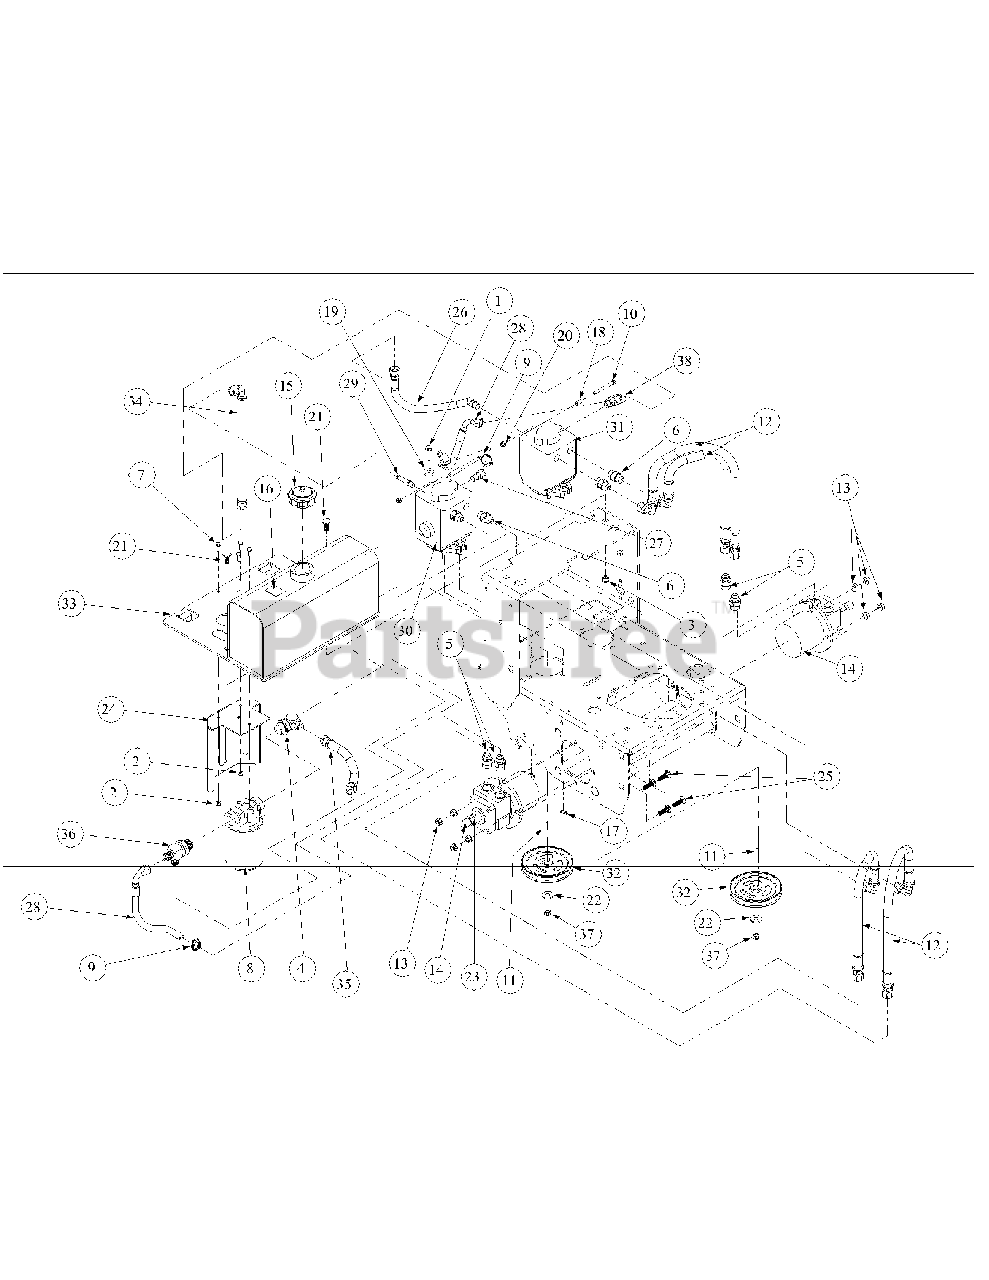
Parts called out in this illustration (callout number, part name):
1	Cap Screw, Standard, 3/8-16 x 1-1/4
2	Lock Nut Nylon Insert, 1/4-20
3	Lock Nut, 3/8-16
4	Elbow 90° 1/2 x 3/4
5	Fitting, Aeroquip
6	Fitting, Aeroquip
7	Cap Screw, 1/4-20 x 3/4
8	Filter Head 3/4
9	Worm Gear Clamp, 5/16-7/8
10	Cap Screw, Socket Head, 1/4-20 x 1-1/2 Zinc
11	Key, 3/16" x 7/8"
12	Reverse Pressure Hydraulic Hose Assembly
13	Flange Lock Hex Nut, 3/8-16
14	Hydraulic Motor, Wheel
15	Cap, Hydraulic Oil Tank
16	Oil Label, 20W-50
17	Lock Nut, 3/8-16
18	Spacer, Pump Release
19	Washer, Idler
20	Hex Lock Nut, 1/4-20
21	Carriage Bolt, 3/8-16 x 1.0
22	Bell Washer, .396 x 1.140 x .095
23	Woodruff Key, 3/16 x 3/4
24	Filter Guard Weldment
25	Carriage Bolt, 3/8-16 x 1.25
26	Left Pump Inlet Hose
27	Push On Fitting 45
28	Right Pump Inlet Hose
29	Push On Straight Fitting
30	Right Hand, Hydro Pump, BDP 10A 308
31	Left Hand, Hydro Pump, BDP 10A 413
32	Hydro Pump Pulley, 5.00 Dia
33	Fuel Tank Mounting Bracket and Integrated Hydraulic Tank
34	Left Hand, 14.25 Return Hose Assembly
35	9.5" Supply Hose Assembly
36	Tee Fitting, 3/4 x 1/2 x 1/2
37	Hex Nut, 3/8-24
38	Tee Fitting
